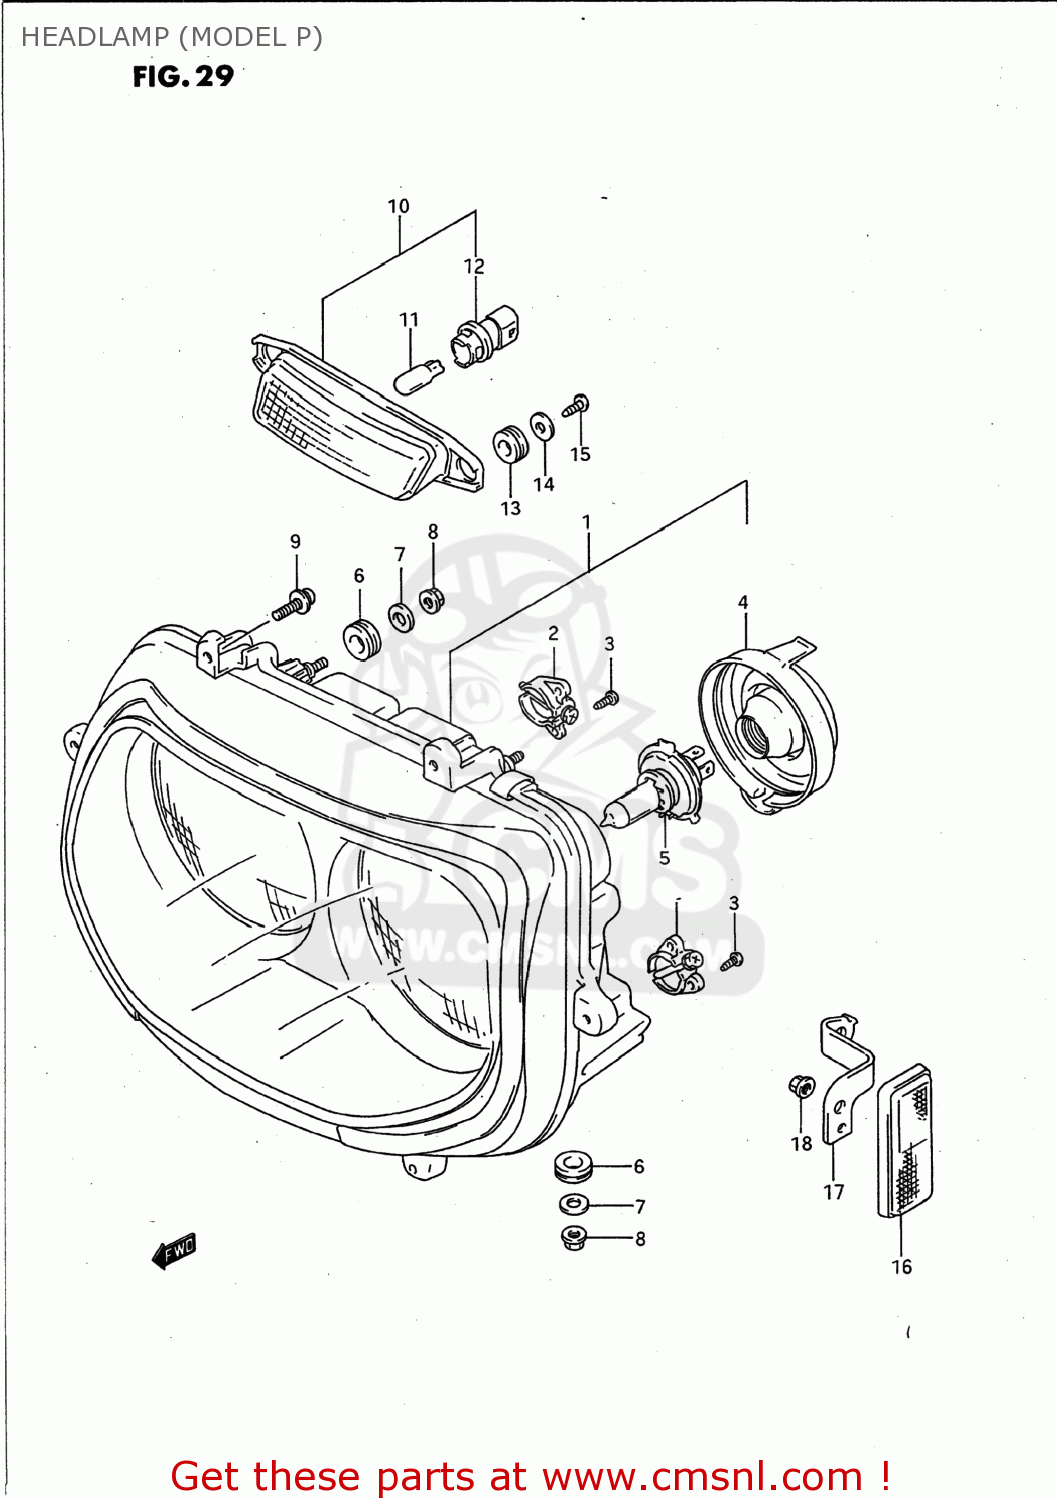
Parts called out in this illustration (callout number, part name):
1	HEADLAMP ASSY
2	GEAR UNIT ASSY,LWR
3	SCREW
4	COVER,SOCKET
5	BULB(12V60/55W,H4)
6	GROMMET
7	WASHER
8	NUT
9	SCREW
10	LAMP ASSEMBLY,FRONT POSITION
11	BULB(12V5W)
12	SOCKET ASSY
13	CUSHION
14	WASHER (4X16X1.2)
15	SCREW
16	REFLEX REFLECTOR,FR SIDE
17	BRACKET,FR SIDE RR,R
18	NUT
